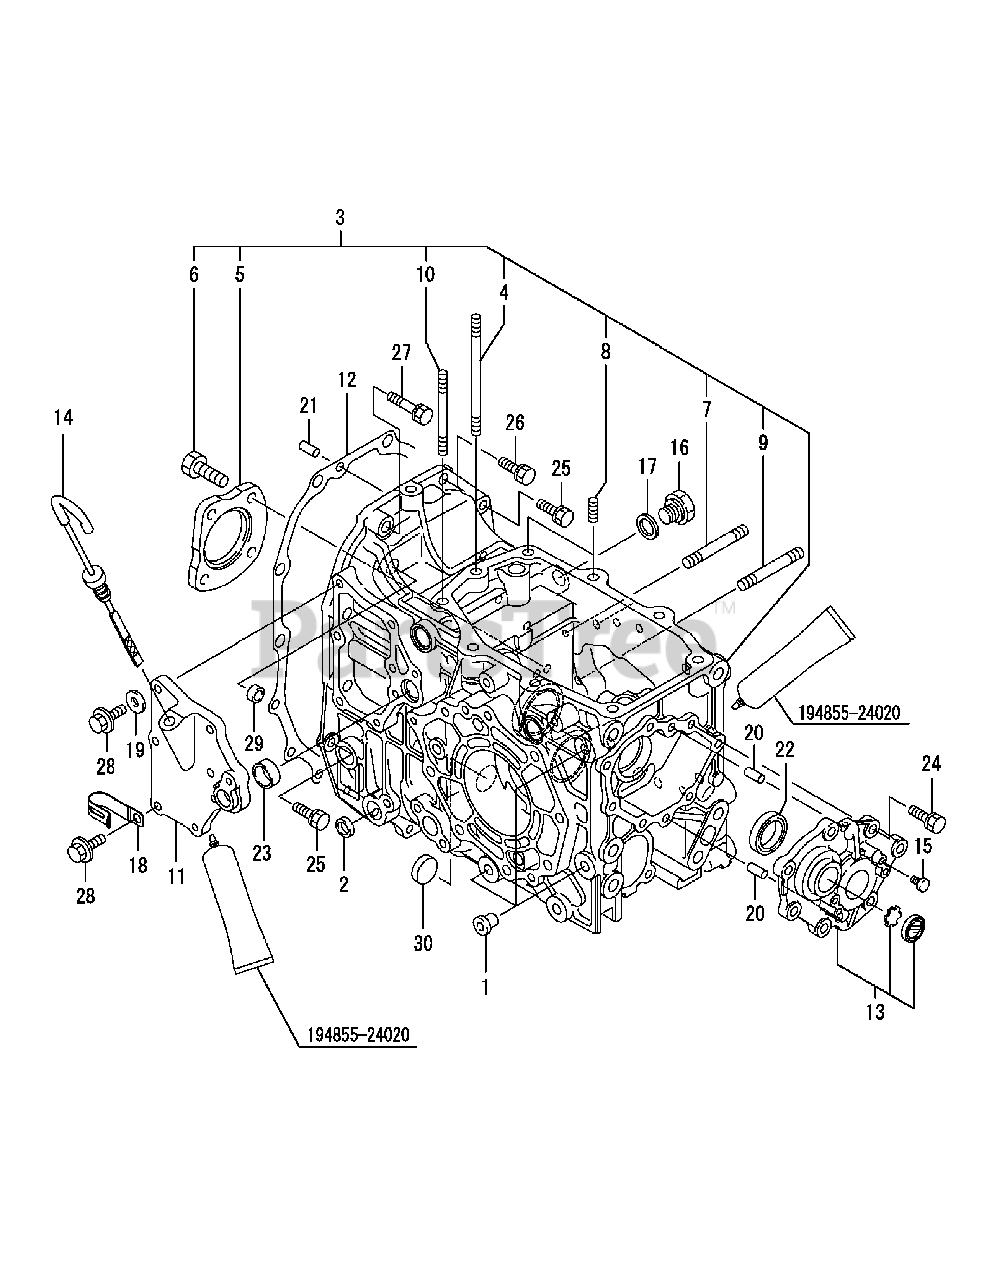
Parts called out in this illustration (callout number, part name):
3	Case Assy, Mission
5	Holder,Bearing
7	Stud,Bolt 8X60
8	Stud,Bolt 10X25
9	Stud,Bolt 10X75
10	Stud,Bolt 10X90
12	Packing,Mission Case
13	Cover Assy,Rear Case
14	Gauge, Oil Level
15	Pin, Cover Hook
18	Clamp,Battery Cable
19	Seal Washer 8(Bolt)
20	Parallel Pin 8X 16
21	Parallel Pin 8X 16
22	Seal Tc28 40 08, Oil
28	Bolt M 8X 25 Plated
